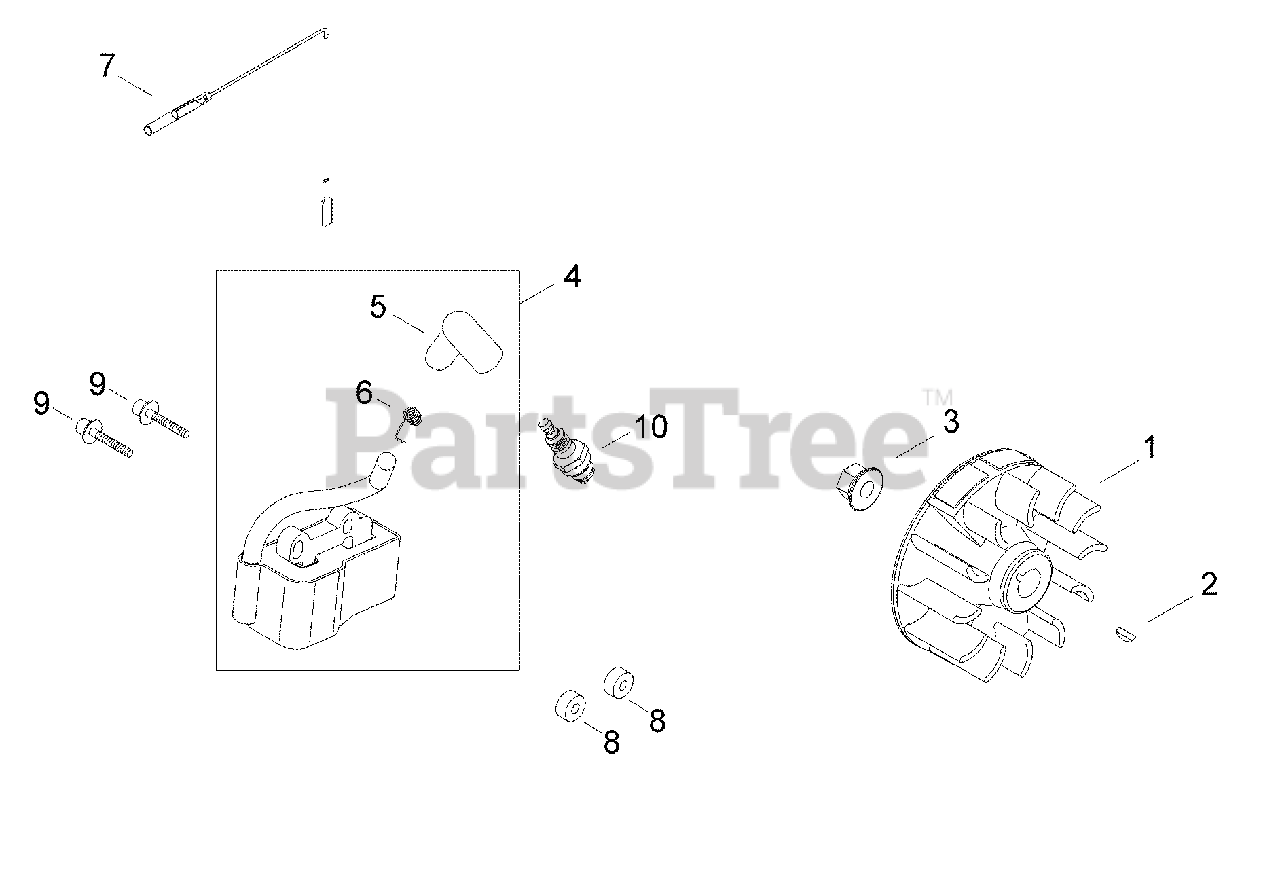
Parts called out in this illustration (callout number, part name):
1	FLYWHEEL
2	KEY, WOODRUFF 3×10
3	NUT M8
4	COIL ASSY, IGNITION
5	CAP, SPARK PLUG
6	TERMINAL, SPARK PLUG
7	LEAD - IGNITION L= 220 MM
8	INSULATOR 4.2×11×6
9	BOLT M4×26
10	SPARK PLUG - CMR5H
